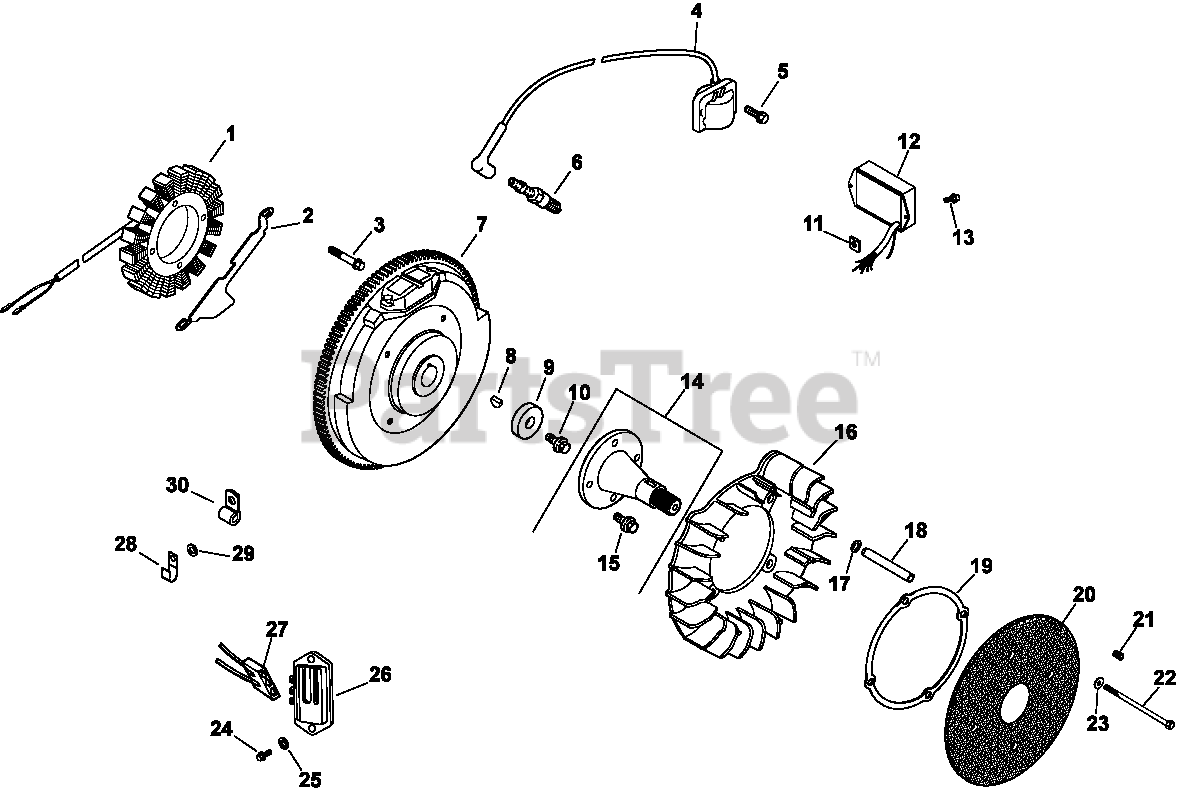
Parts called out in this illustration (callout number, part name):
1	KIT, 15 / 20 AMP STATOR
2	BRACKET, STATOR WIRE
3	SCREW, M5X0.8X25 - (#25086402S)
5	SCREW, SKT THD FRM M5X0.8X25
6	PLUG, SPARK (STD)
7	FLYWHEEL, PAINTED-USE 24 025 56-S
8	KEY, 3/16" X 5/8"
9	WASHER, FLAT 13/32"
10	SCREW, FLG M10X1.5X45 - (#25086361S)
11	NUT, PLASTIC
12	MODULE, SPEED ADVANCE
13	SCREW, PHL HD #11-16X1/2"
14	SHAFT, FRONT DRIVE
15	SCREW, FLG M8X1.25X25
16	FAN (WITH HOLE)-USE 24 157 16-S
17	WASHER, SPRING 10 MM
19	RING, SUPPORT USE 25 141 08-S
21	SCREW, SKT SET #10-24X1/4"
22	SCREW, CAP M6X1.0X99.5
23	WASHER, FLAT 1/4" (O.D. 5/8")
24	SCREW, PHL HD #11-16X7/8"
25	WASHER, FLAT 3/16"
27	CONNECTOR, BODY (KM)-USE 25 155 41-S
28	CLIP, CABLE
29	WASHER, FLAT 1/4" (O.D. 1/2")
